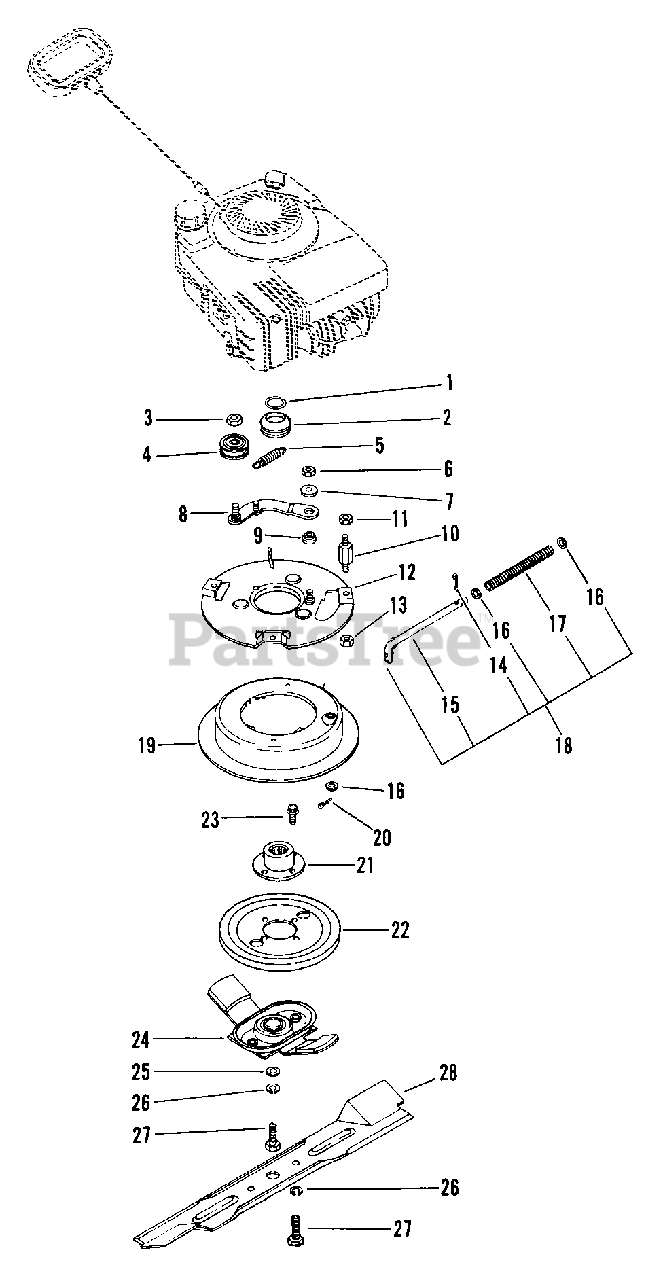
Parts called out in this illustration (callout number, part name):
1	RG-RTNG-EXT.875X.075
2	SHEAVE-BBC
3	NUT-LK-CTR .375-16 GR A PL
4	IDLER-FLAT 1.50 X .39 CLARK
5	SG-TENS .48X.44X2.0 5.0 WLD
6	NUT-LK .312-18 GR A PL
7	WSHR-FL-STL .328X1.0X.094 PL
8	IDLER ARM WELDMENT BBC
9	BSHG, FLG .325X.499X.26X.88
10	HEX STUD BBC
11	NUT-LK TOP .375-16 GR C YWZC
12	BBC RAMP ASSY
13	NUT-FLG. .312-18 PL
14	PIN-HAIR INT .06X.18X.77
15	ROD,RETURN BBC
16	WSHR-FL-STL .328X.555X.06 PL
17	SG-COMP .080X.550X8.50 WLD38
18	ROD RETURN ASSEM.
19	ACTUATOR,BRAKE
20	PIN-COTR .06X.50
21	FLYWHEEL HUB
22	FLYWHEEL
23	SCR-TAP .250-20X.50 HXSLHDPL
24	BBC LEAF SPRING AND BEARING AS
25	WSHR-FL-STL .382X1.25X.130
26	WSHR-LK .375X.115 HVY PL
27	BLT-HEX .38-24X1.25 PL GR5
28	BLADE, 21" MOWER
